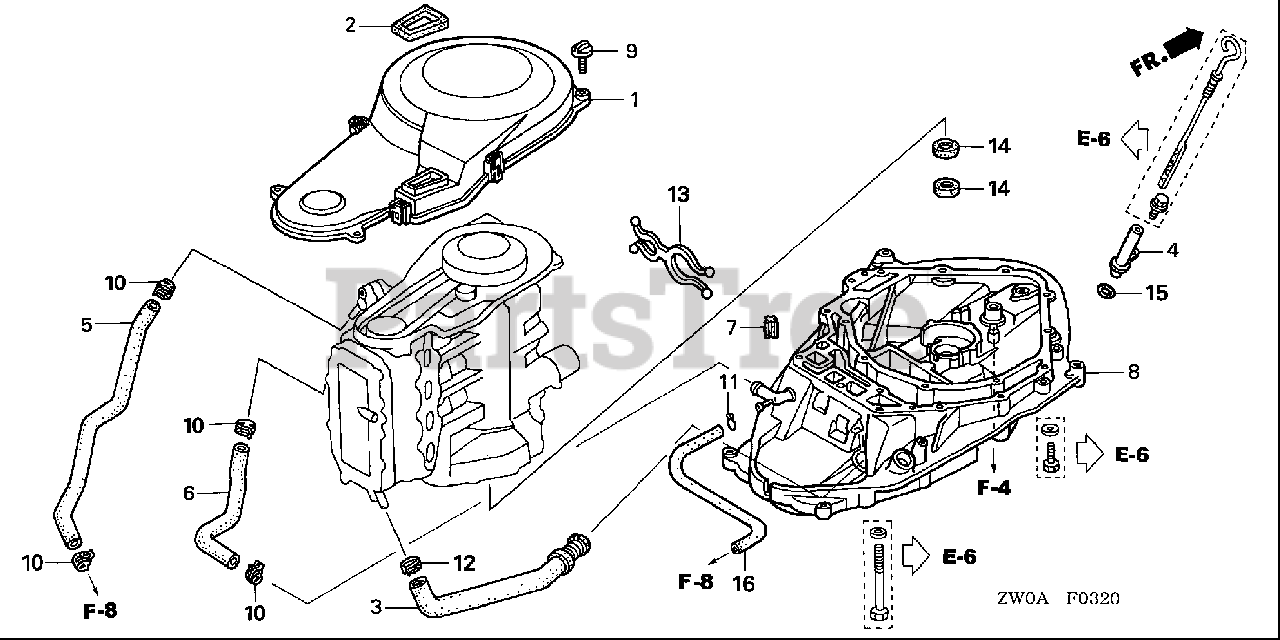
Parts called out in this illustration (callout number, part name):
1	COVER, TIMING BELT (UPPER)
2	RUBBER, SEAL
4	PIPE, OIL LEVEL
5	HOSE, FLUSHING WATER
6	HOSE, WATER BYPASS
7	RUBBER, SEAL
8	CASE, MOUNT *NH8* (DARK GRAY)
9	BOLT, TIMING BELT COVER
10	CLAMP, TUBE (D18.8)
11	CLIP, TUBE (B8)
12	CLAMP, TUBE (D21)
13	CLIP, PURSE LOCK
14	SEAL, WATER (22X35X7)
15	O-RING (11.5X3.5)
16	BULK HOSE, VACUUM (4.5X1000) (4.5X430)
17	CLIP, SEAL RUBBER
